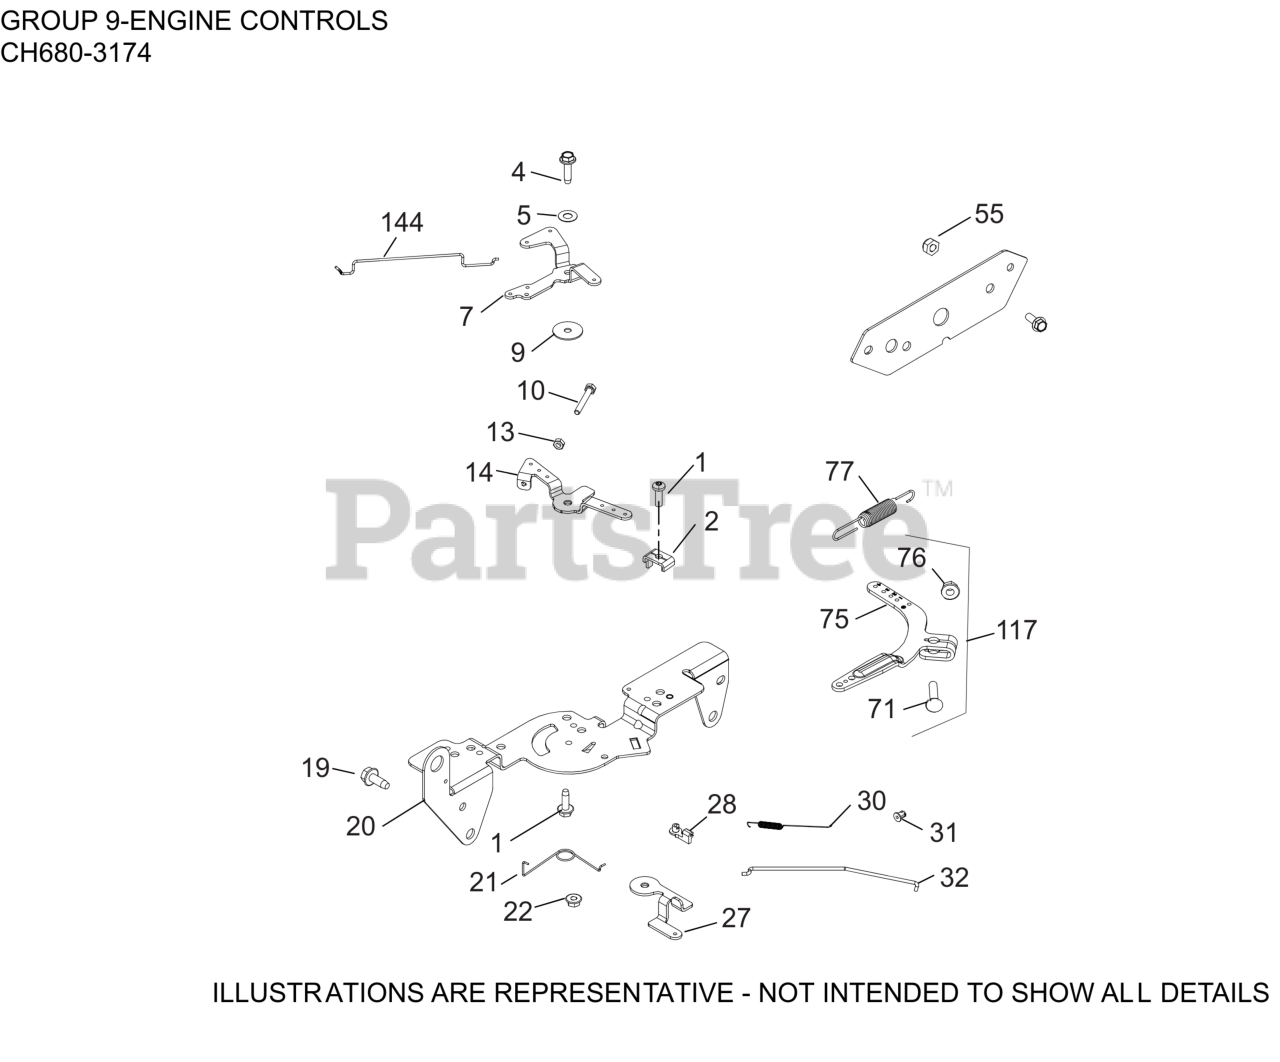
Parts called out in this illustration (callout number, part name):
1	SCREW, THREAD FORMING
2	CLAMP, CABLE CABLE
4	SCREW, THD FRM-USE 25 086 473-S
5	WASHER, SPRING 1/4"
7	LEVER, CHOKE
9	WASHER, FLAT 5.5 MM
10	SCREW, CAP M4X.7X30
13	NUT, M4X0.7
14	LEVER, THROTTLE CONTROL
19	SCREW, THREAD FORMING
20	BRACKET, CONTROL
21	SPRING, CHOKE RETURN
22	NUT, LOCK M5X.8
27	LEVER, THROTTLE ACTUATOR
28	BUSHING, THROTTLE LINKAGE
30	SPRING, LINKAGE
31	BUSHING, LINKAGE RETAINING
32	LINKAGE, THROTTLE
55	NUT, LOCK M6X1.0
71	BOLT, RD HD SQ NECK M6X1.0X25
75	LEVER, GOVERNOR - (#2409069S)
76	NUT, FLG M6X1.0
77	SPRING, GOVERNOR (CLEAR)
117	LEVER, GOVERNOR ASSEMBLY
144	LINKAGE, CHOKE
